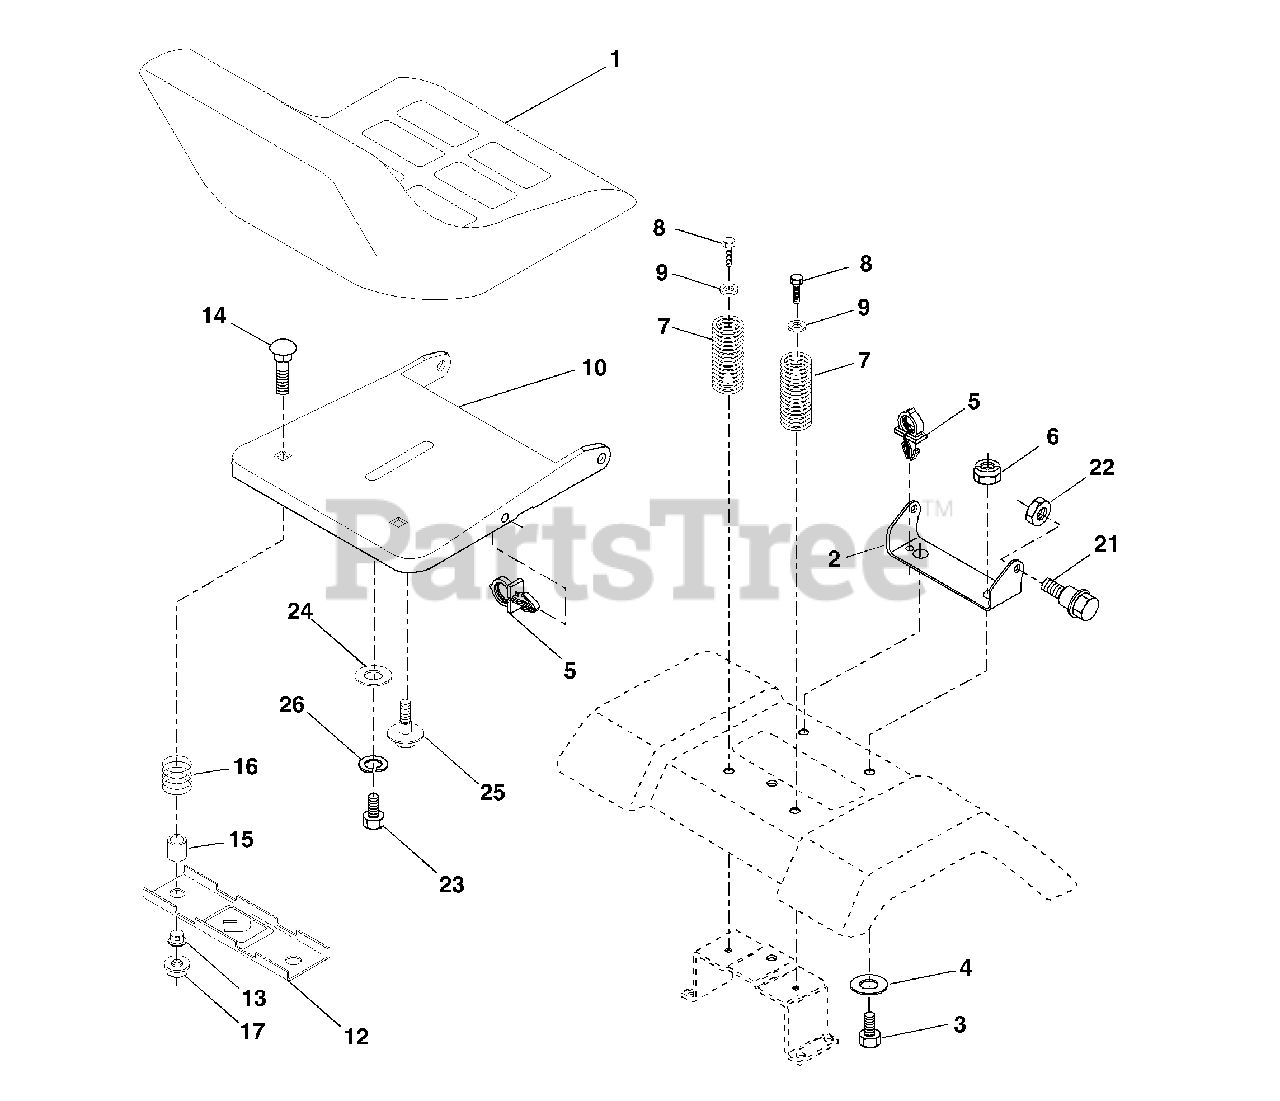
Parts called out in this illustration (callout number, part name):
1	Seat
2	Bracket Pnt Pivot Seat (blk )
3	Bolt
4	Washer 13/32 x 1 x 10 Ga
5	Clip Push-In Hinged
6	Nut
7	Spring Seat Cprsn 2 250 Blk Zi
8	Screw 3/8-16 x 1.5
9	Washer 13/32 x 1 x 14 Ga
10	Pan Pnt Seat (blk )
12	Bracket Pnt Mounting Switch
13	Bushing Snap Blk Nyl 50 Id
14	Bolt Rdhd Sht Nk 1/4-20 x 1-1/2
15	Spacer Split 28 x 96 Yel Zinc
16	Spring Cprsn 1 27 Blk Pnt
17	Nut Lock 1/4 Lge Flg Gr 5 Zinc
21	Bolt Shoulder 5/16-18 Unc Blkz-2A
22	Nut
23	Bolt Hex Black
24	Washer 17/32 x 1-3/16 x 12 Ga
25	Bolt Shoulder 5/16-18 x 62
26	Lockwasher
